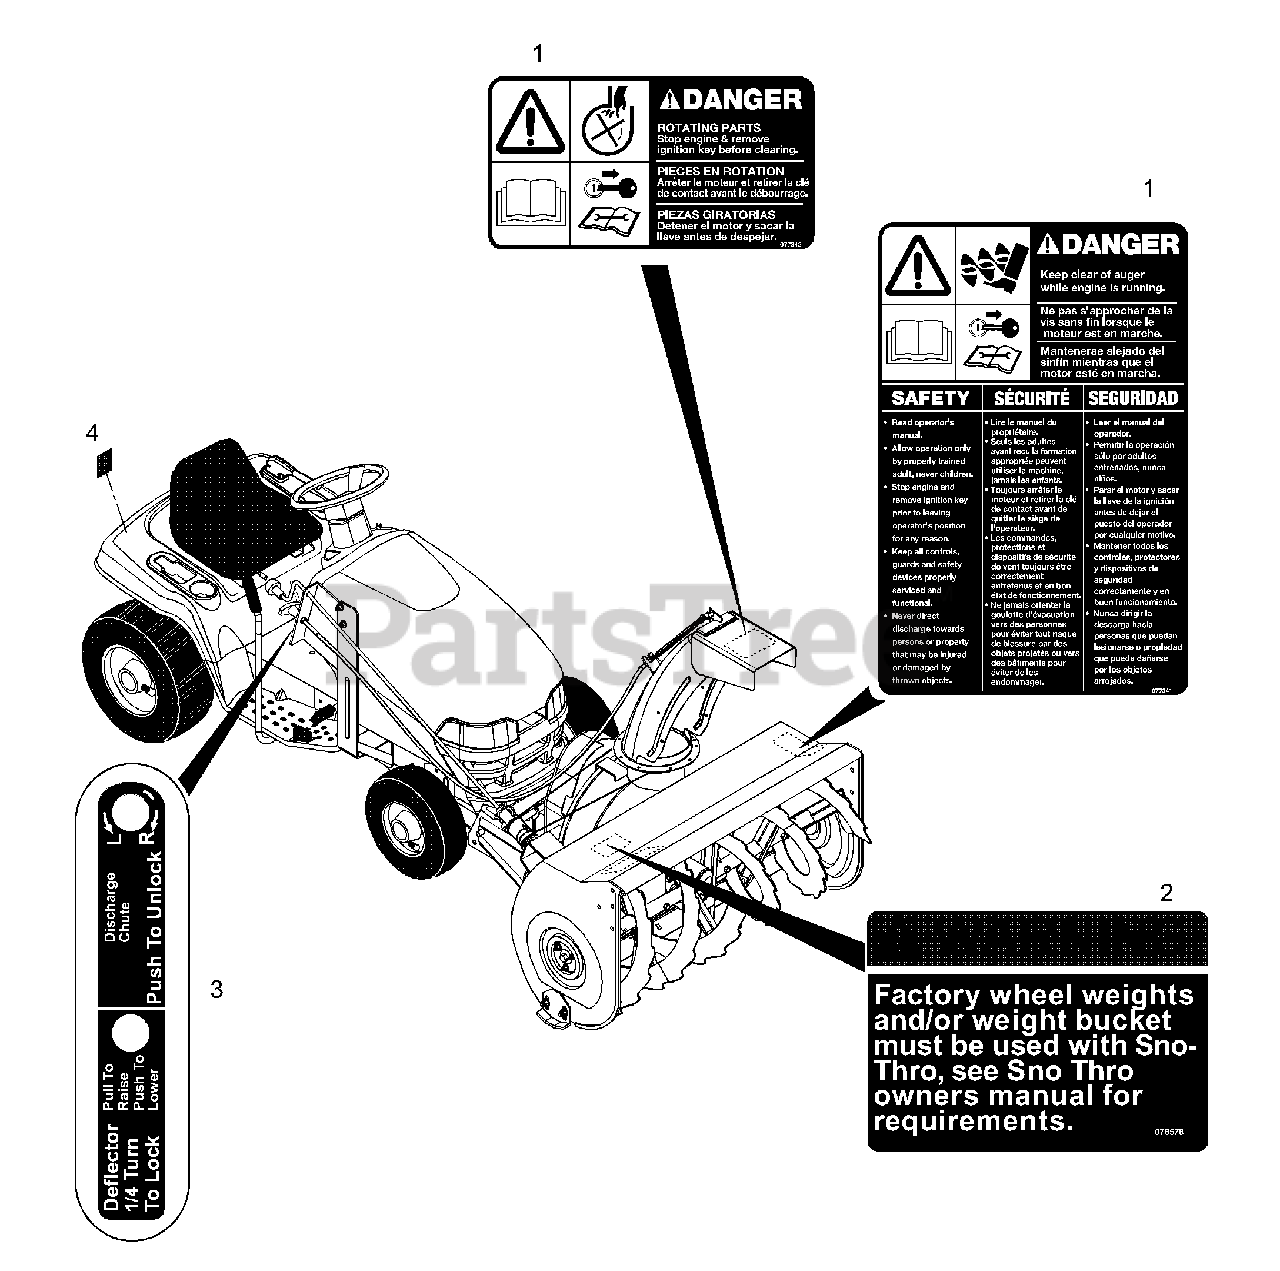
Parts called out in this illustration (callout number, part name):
1	Decal Set-DANGER
2	Decal-Wheel Weight
3	Decal-Chute Crank
4	Reflex Reflector
